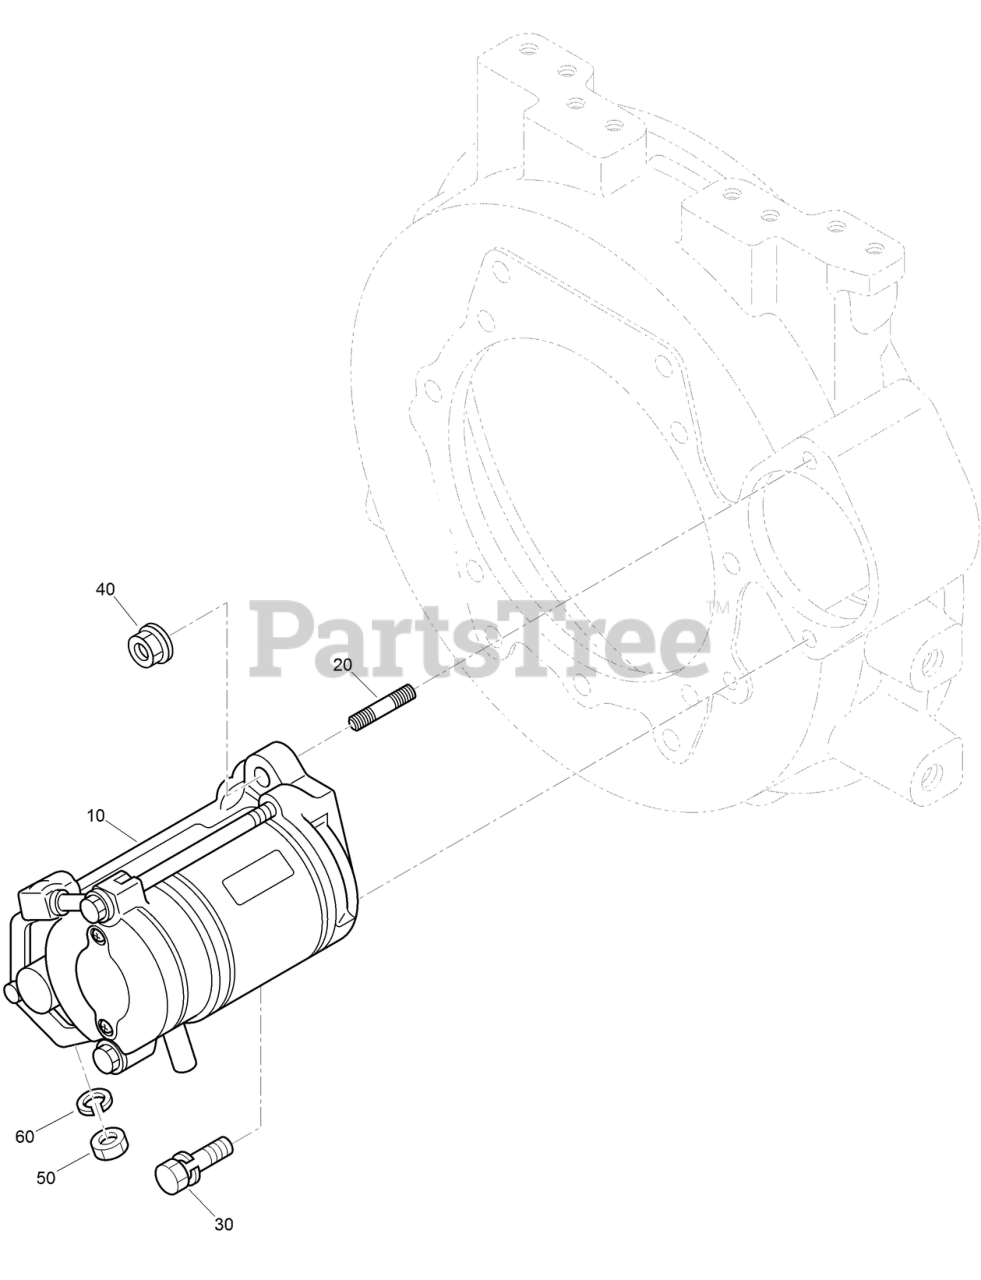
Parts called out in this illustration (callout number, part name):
10	STARTER ASM
20	BOLT-STUD
40	NUT-FLANGE
60	WASHER-SPRING, LOCK
